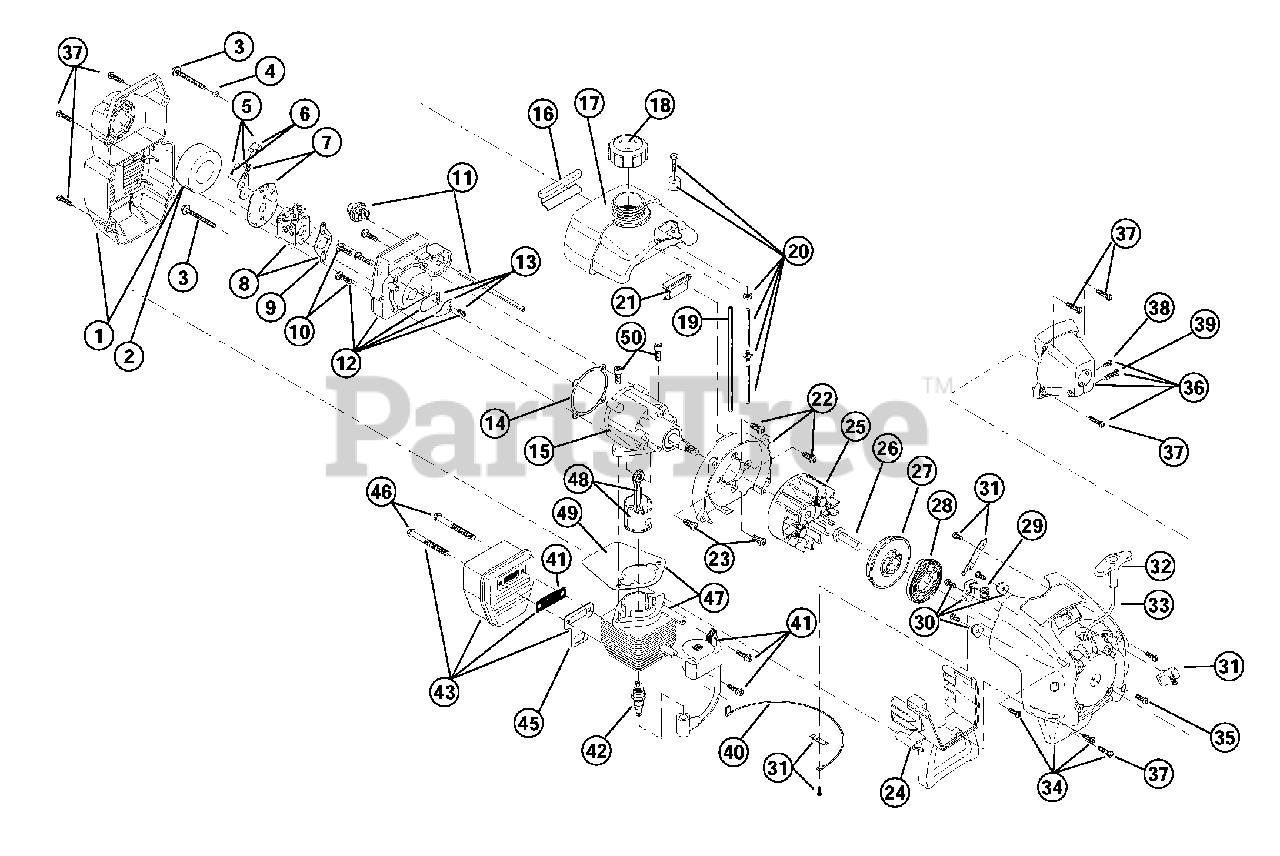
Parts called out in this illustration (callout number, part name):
1	Air Cleaner/Muffler Cover Assembly
2	Air Cleaner Filter
3	Carburetor Mounting Screw Assembly
4	Wavey Washer
5	Choke Lever Assembly
6	Choke Knob and Screw
7	Choke Lever and Plate
8	Carburetor Assembly
9	Carburetor Gasket
10	Carb Mount Screw
11	Primer and Hose Assembly
12	Carb Mount Assembly
13	Reed Assembly
14	Carburetor Mount Gasket
15	Crank Case Service Assembly
16	Rear Mounting Pad
17	Fuel Tank Assembly
18	Fuel Cap Assembly
19	Fuel Return Line
20	Fuel Line Assembly
21	Front Mounting Pad
22	Shroud Assembly
23	Shroud Screw
24	Shroud Extension and Stand
25	Flywheel Assembly
26	Spacer
27	Recoil Pulley Assembly
28	Recoil Spring
29	Rope Guide
30	Pulley Retainer Assembly
31	Switch Assembly
32	Pull Handle
34	Starter Housing Assembly
35	Housing Screw
36	Clutch Cover Assembly
37	Cover Screw
38	Anti-Rotation Screw
39	Clamping Screw
40	Wire Lead
41	Module Assembly
42	Spark Plug
43	Muffler Assembly
44	Spark Arrestor Screen
45	Exhaust Gasket
46	Muffler Mounting Bolt Assembly
47	Cylinder Assembly
48	Piston and Rod Assembly
49	Cylinder Gasket
50	Cylinder Bolt
